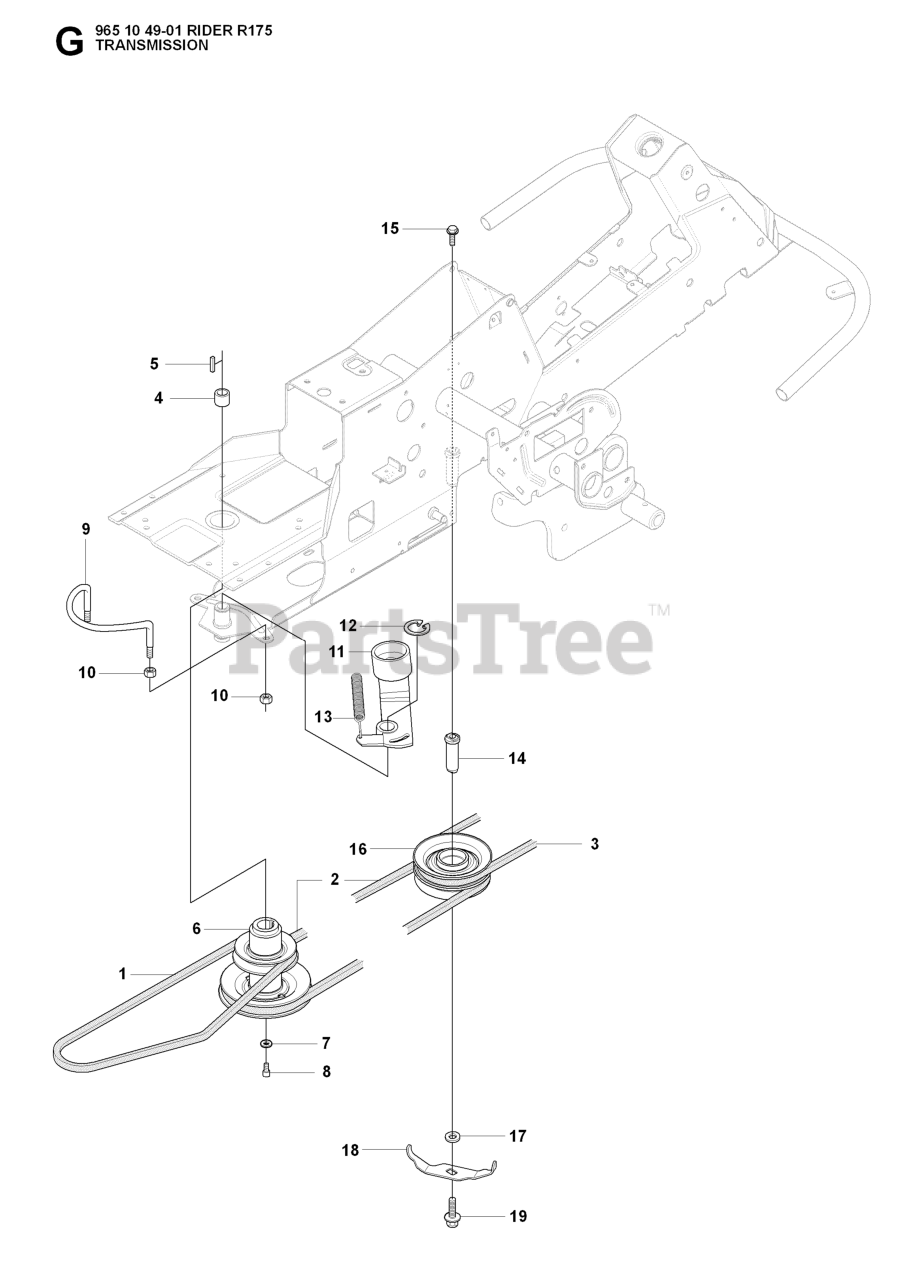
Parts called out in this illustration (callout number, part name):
1	BELT
2	BELT
9	BELT GUIDE
10	NUT
12	RETAINING RING SGA 25
14	SHAFT
18	BELT GUIDE
19	BOLT
